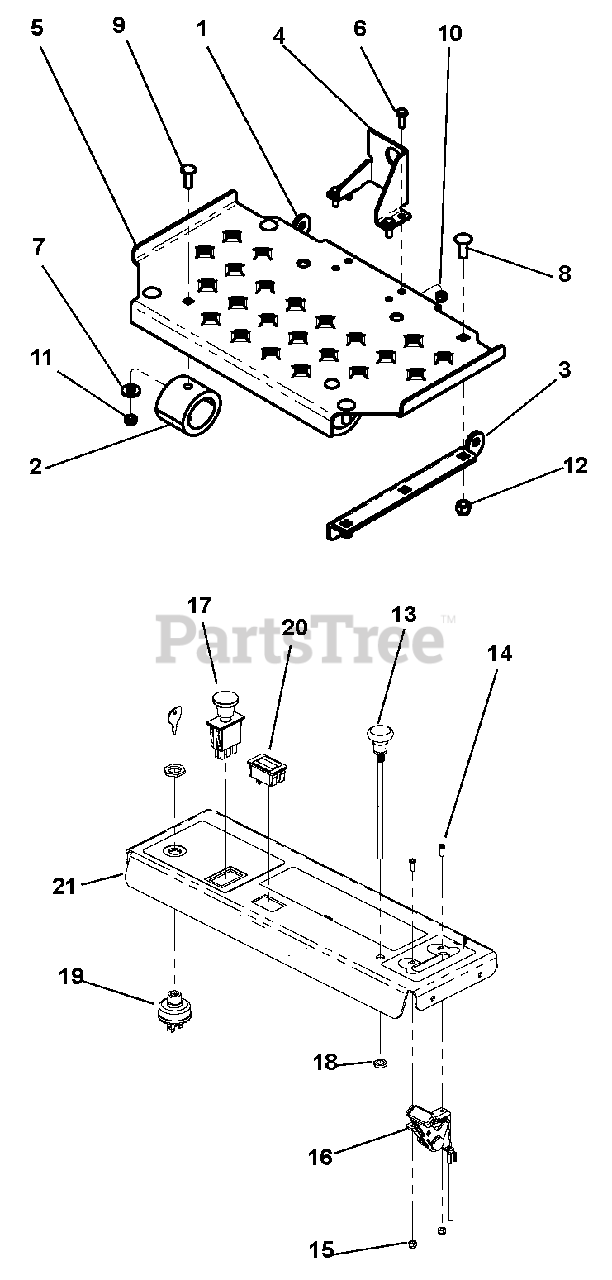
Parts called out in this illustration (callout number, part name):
1	Plate, Platform Tab LH
2	Bumper, Miner GBR-6
3	Plate, Platform Tab Left Hand
4	Anchor, Operator Presence Control
5	Platform
6	Bolt, Hex .25-20 x .75 Grade 5
7	Washer, Flat-Steel .38 x .875 x .083
8	Bolt, .375-16 x 1.00 Round Head Square Neck G 5
9	Bolt, .312-18 x 1.00 Round Head Square Neck Grade 5
10	Nut, Locking-Nylon .25-20
11	Nut, Locking-Nylon .312-18
12	Nut, Locking-Nylon .38-16
13	Cable, Choke
14	Screw, 8-32 x .50 Pan PHL Y
15	Nut, 8-32 Elastic Stop
16	Cable, Throttle
17	Switch, PTO Engagement
18	Nut, Hex .38-16
19	Switch, Key - 3 Position
20	Meter, Hour Digital
21	Top, Console w/Decals
